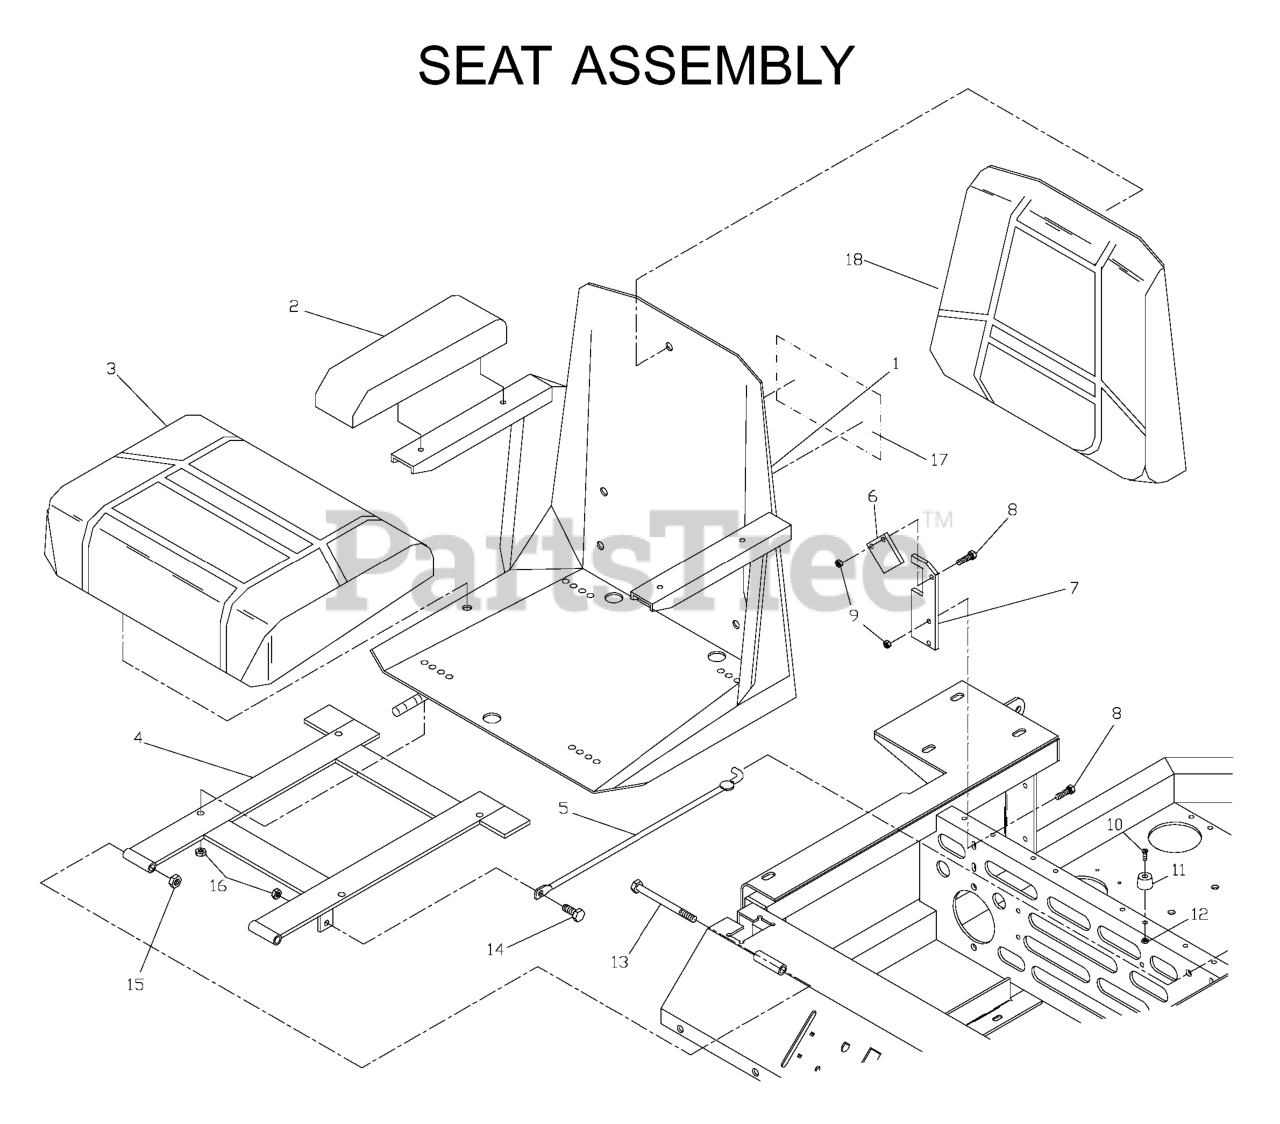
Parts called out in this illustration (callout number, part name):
1	SEAT, COMPLETE
2	ARM REST CUSHIONS/PAIR
3	SEAT CUSHION W/SWITCH
4	SEAT MOUNT FRAME
5	SEAT STOP ROD
6	SEAT LATCH
7	SEAT LATCH MOUNT
8	HCS 1/4C X 3/4 HCS
9	NUT 1/4C CENTERLOCK
10	SCREW, #1--24 X 1/2 SLOTTED
11	SEAT BUMPER
12	NUT 10-24 NYLOC
13	SCREW, 3/8C X 5 HEX CAP
14	HCS 5/16C X 1
15	NUT 3/8C CENTERBLOCK
16	NUT 5/16C CENTERLOCK
17	DECAL, CROWN H
18	SEAT, BACK CUSHION
